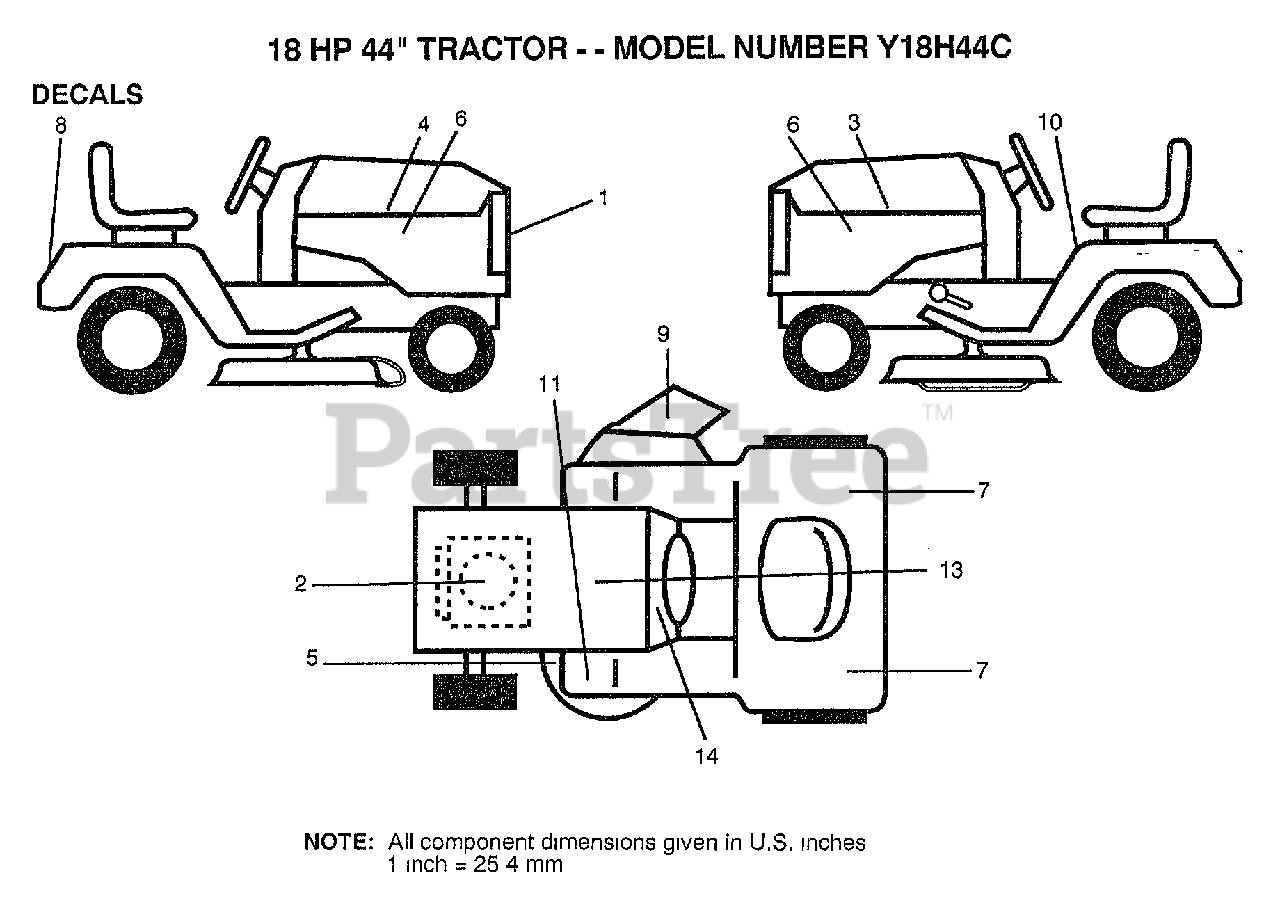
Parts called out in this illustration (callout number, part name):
1	DECAL.GRILL.YARDP
2	"DECAL,HP ENGINE"
3	DECAL HOOD LH
6	DECAL.PANEL.SIDE
7	REFLECTOR-TAIL YT
9	"DECAL, WARNING"
10	DECAL CAUTION
11	DECAL T
13	DECAL
14	DECAL.DASH.INSTR.
